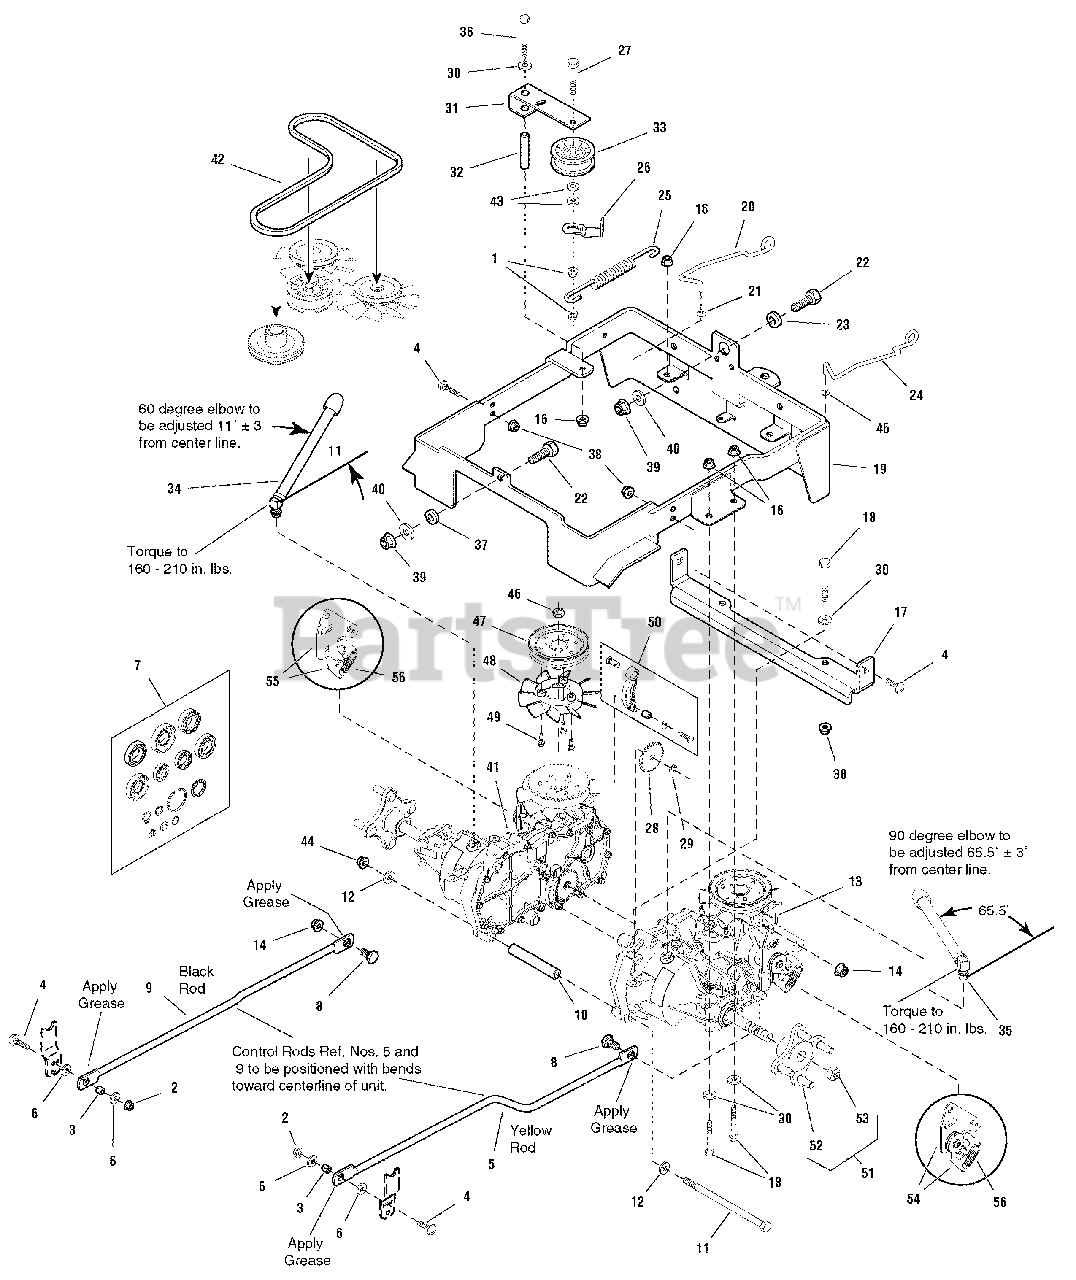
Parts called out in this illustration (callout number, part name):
1	NUT, Hex Flange ESNA, 3/8-16
2	NUT, Hex Keps, 5/16-18
4	BOLT, Carriage, 5/16-18 x 1 1/4
5	ROD, Control, L.H.
6	WASHER, 5/16
7	HYDRO SEAL KIT
8	BOLT, Shoulder, 7/16-14, G5
9	ROD, Control, R.H.
11	CAPSCREW, Hex Head, 7/16-14 x 8, G5
12	WASHER, 7/16
13	TRANSMISSION, Hydro Gear, L.H.
14	NUT, Hex Flange, 7/16-14, Two-Way Lock
16	NUT, Hex Flange, 5/16-18 ESNA
17	SUPPORT, Center Transmission
18	CAPSCREW, Hex Head, 5/16-18 x 2-3/4, G5
19	FRAME ASSEMBLY, Carrier Transmission
20	ROD, Actuator, R.H. E-Coat
21	CLIP, Rod End Clevis L.H.
22	CAPSCREW, Hex Head, 1/2-13 x 1-1/4, G5
24	ROD, Actuator, L.H.
25	SPRING, Extension
26	GUARD, Belt
27	CAPSCREW, Hex Head, 3/8-16 x 2-1/4, G5
28	GEAR, Parking Brake, Transmission
29	CLIP, E Transmission Parking Brake
30	WASHER, 5/16
31	ARM, Idler
32	SPACER, Powdered Metal
33	PULLEY, Idler
34	KIT, Breather 60 Degree Elbow
35	KIT, Breather 90 Degree Elbow
36	CAPSCREW, Hex Head, 5/16-18 x 2-1/2, G5
38	NUT, Hex Whiz Lock Flange, 3/8-16
39	NUT, Hex Flange, Two-Way Lock, 1/2-13
40	WASHER, 1/2
41	TRANSMISSION, Hydro Gear, R.H.
43	WASHER, 3/8
44	NUT, Hex Centerlock Jam, 7/16-14
45	CLIP, Rod End Clevis R.H.
46	NUT, Hex Head Center Lock
47	PULLEY, 4.5", Transmission
48	FAN, 6", Transmission
49	CAPSCREW, Hex Head, Transmission
50	PARKING BRAKE ARM ASSEMBLY, Transmission L.H. or R.H.
51	HUB REPLACEMENT KIT
52	HUB, EZT Transmissions
53	NUT, EZT Transmissions
54	ARM, Control Kit L.H.
55	ARM, Control Kit R.H.
56	SPRING, Extension
